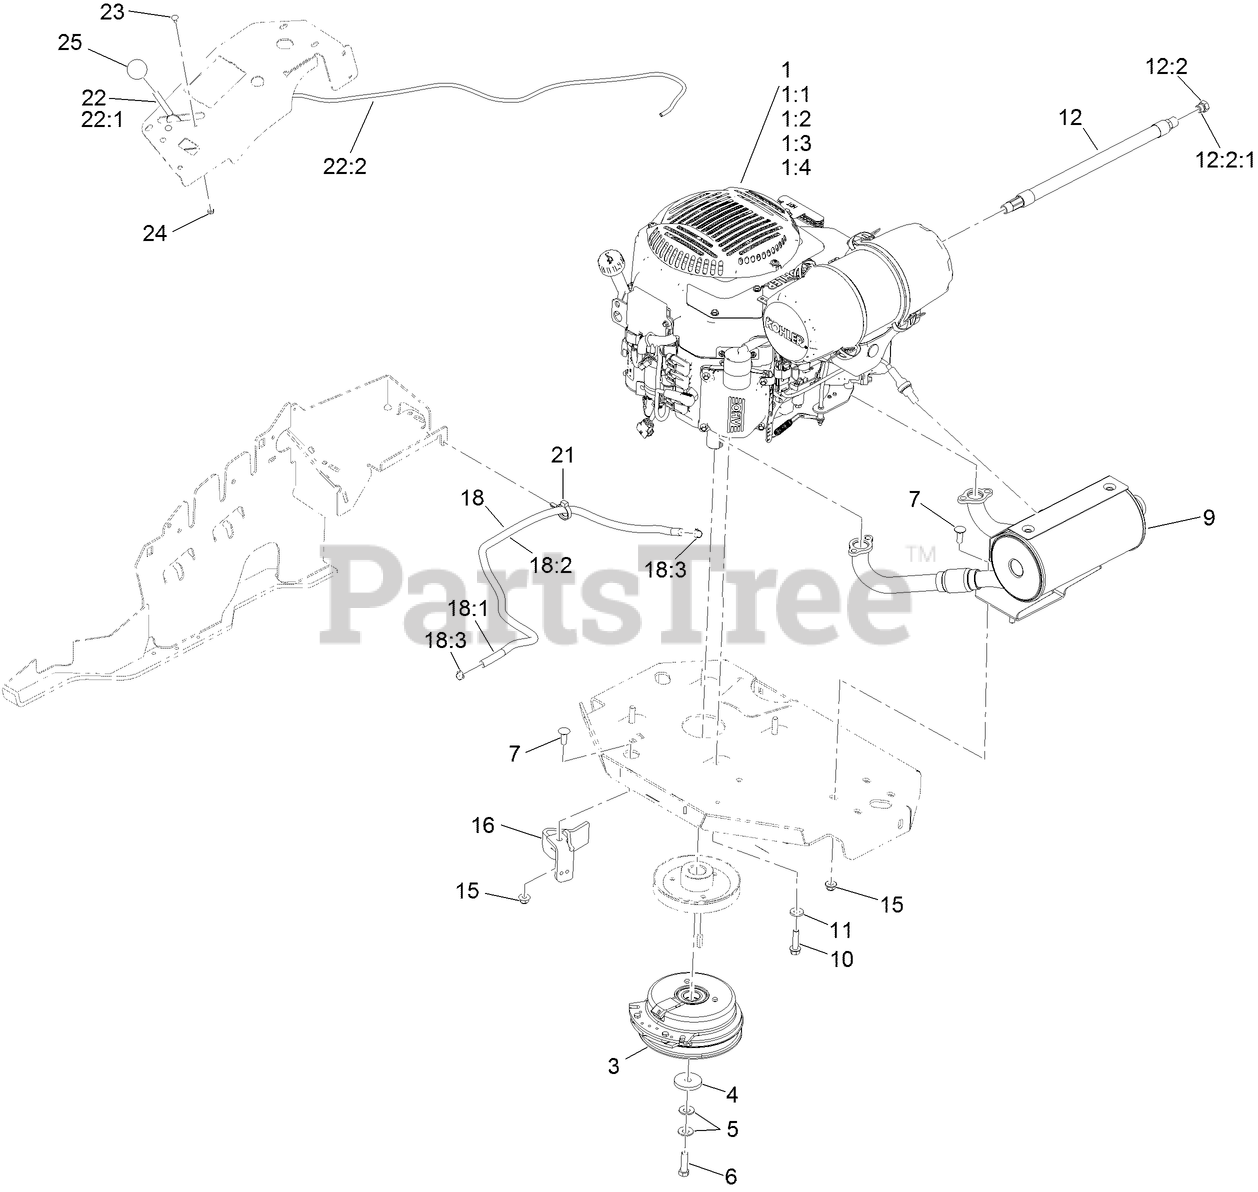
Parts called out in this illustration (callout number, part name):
1:1	KOHLER 52 050 02-S ENGINE OIL FILTER
1:2	KOHLER 25 083 01-S ENGINE AIR FILTER
1:3	KOHLER 25 083 04-S SAFETY FILTER
1:4	KOHLER 25 050 42-S FUEL FILTER
3	CLUTCH KIT
4	WASHER-CLUTCH
5	WASHER-SPRING
6	SCREW-HH, W/LOCTITE
7	SCREW-CARR
9	KIT,MUFFLER
10	SCREW-HWH
11	WASHER-BELLEVILLE
12	OIL DRAIN HOSE ASM
12:2	PLUG-HH
12:2:1	O-RING
15	NUT-HF, NI
16	CLUTCH-ANCHOR
18	FUEL LINE ASM
18:1	HOSE-FUEL
18:2	SLEEVE-THERMAL
18:3	CLAMP-HOSE
21	CLAMP-HOSE
22	THROTTLE CONTROL ASM
22:1	LEVER-THROTTLE
23	BOLT-CARR
24	NUT-LOCK, NI
25	KNOB-BALL
